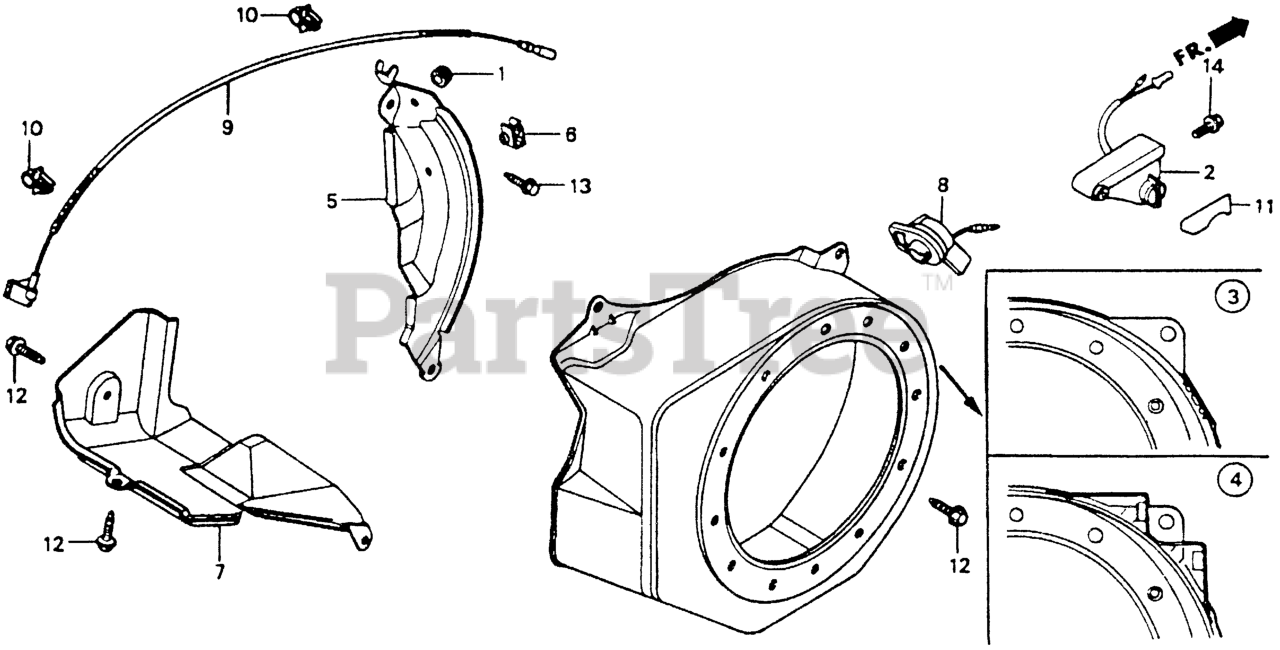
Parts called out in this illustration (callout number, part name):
3	COVER, FAN *R8* (BRIGHT RED)
3	COVER, FAN *R280* (POWER RED)
5	PLATE, SIDE (STD)
6	CLAMP, CORD
7	SHROUD
8	SWITCH ASSY., ENGINE STOP Use from Engine SN 2092216 to 2359126.
9	WIRE, STOP SWITCH
9	WIRE, STOP SWITCH (370MM)
10	HOLDER, STOP SWITCH WIRE Use up to Engine SN 2056819.
12	BOLT, FLANGE (6X12) (CT200)
13	BOLT, FLANGE (6X20) (CT200)
